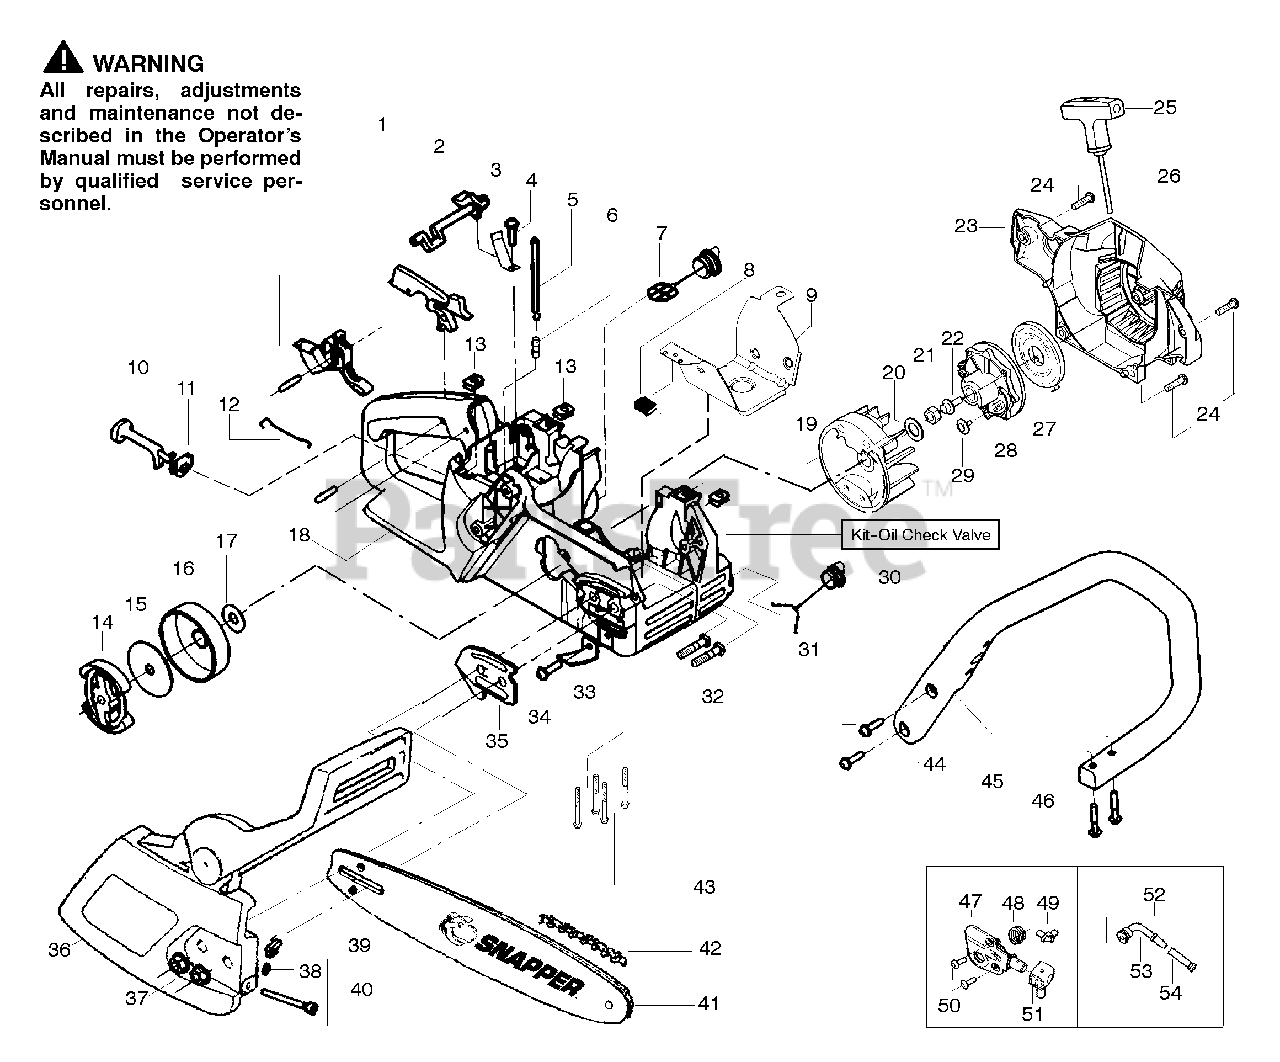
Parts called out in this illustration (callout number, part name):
1	Kit-Trigger & Lockout
2	Lever-Switch
3	Spring-Switch
5	Kit-Fuel Line (Large)
6	Fitting-Fuel line
7	Assy-Fuel Cap w/ret.
8	Clip-"U"
9	Shield-Heat
10	Lever-Choke
11	Grommet-Choke lever
12	Wire-Throttle
13	Nut-Speed
14	Assy.-Clutch
15	Washer-Clutch
16	Assy-Drum W/brg.
17	Washer-Thrust
18	Assy-Chassis
19	Assy-Flywheel
20	Washer-Flywheel
21	Nut-Flywheel
23	Housing-Fan
25	Handle-Starter
26	Kit-Rope
27	Spring-Starter
28	Pulley-Starter
30	Kit-Oil Check Valve
31	Assy-Oil Cap
32	Bolt-Bar
33	Chain Catcher
35	Plate-Bar Mounting
36	Assy.-Chain Brake
37	Nut-Bar Mounting
38	Retainer-Bar Adjust
39	Pin-Bar Adjust
40	Kit-Bar Adjust
42	Chain-18"
45	Handle-Front
47	Kit-Oil Pump
48	Gear-Worm Spring
49	Elbow-Oil Pickup
51	Block-Seal
52	Assy-Oil-Pickup
53	Pickup-Oiler
54	Filter-Oil
